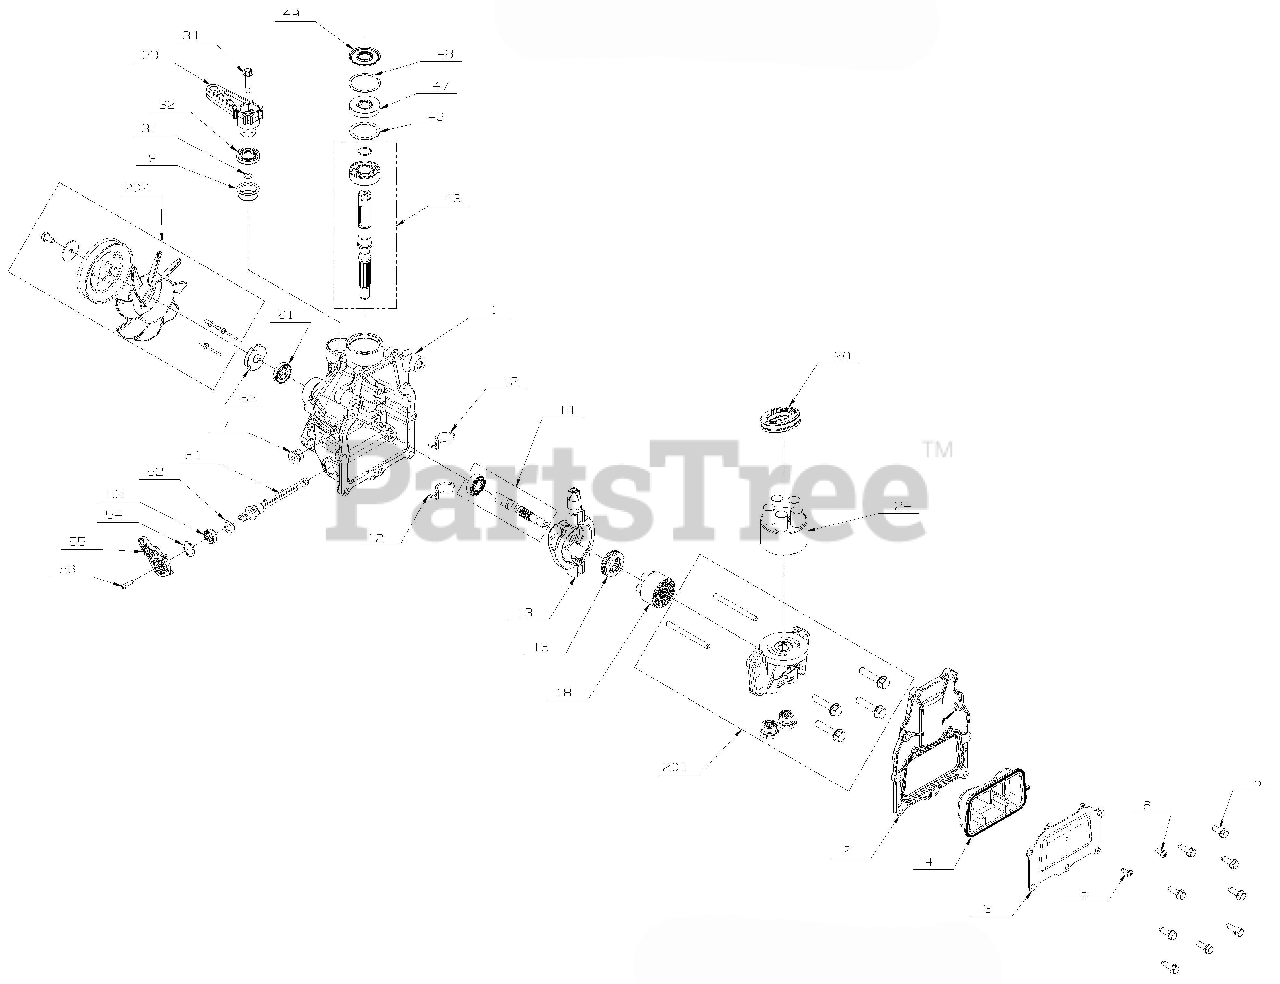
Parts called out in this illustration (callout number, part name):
1	HOUSING, MAIN, SHOT
2	COVER
3	PLATE, EXPANSION
4	BLADDER
5	HFHCS 1/4-20X.75
7	PLUG, 9/16-18 STR THREAD SOCKET HEAD
9	GUIDE, PLASTIC ALIGNMENT
12	BEARING, CRADLE
13	SWASH PLATE
14	KIT, INPUT SHAFT
18	KIT, 3cc BLOCK
24	KIT, 10 CC BLOCK
28	BEARING. THRUST 30 X 52 X 13
33	ARM, CONTROL
34	SCREW,HEX WASHER 1/4-20X1.125
43	KIT, MOTOR SHAFT
46	WASHER 1.23X1.56X.04
48	RING, M40, RET, INT
49	SLEEVE, SEAL GUARD
51	ACTUATOR, BYPASS
52	WASHER, 345 X .73 X .01, SPRING
53	SEAL, LIP .375X.75X.25
54	RING, RET .750
55	ARM, BYPASS
56	SCREW, M4 X 16, WUPLAST
62	HUB, PULLEY DIA 1.41
200	KIT, SEAL
201	KIT, CENTER SECTION
202	KIT, RT-310 FAN REPLACEMENT
